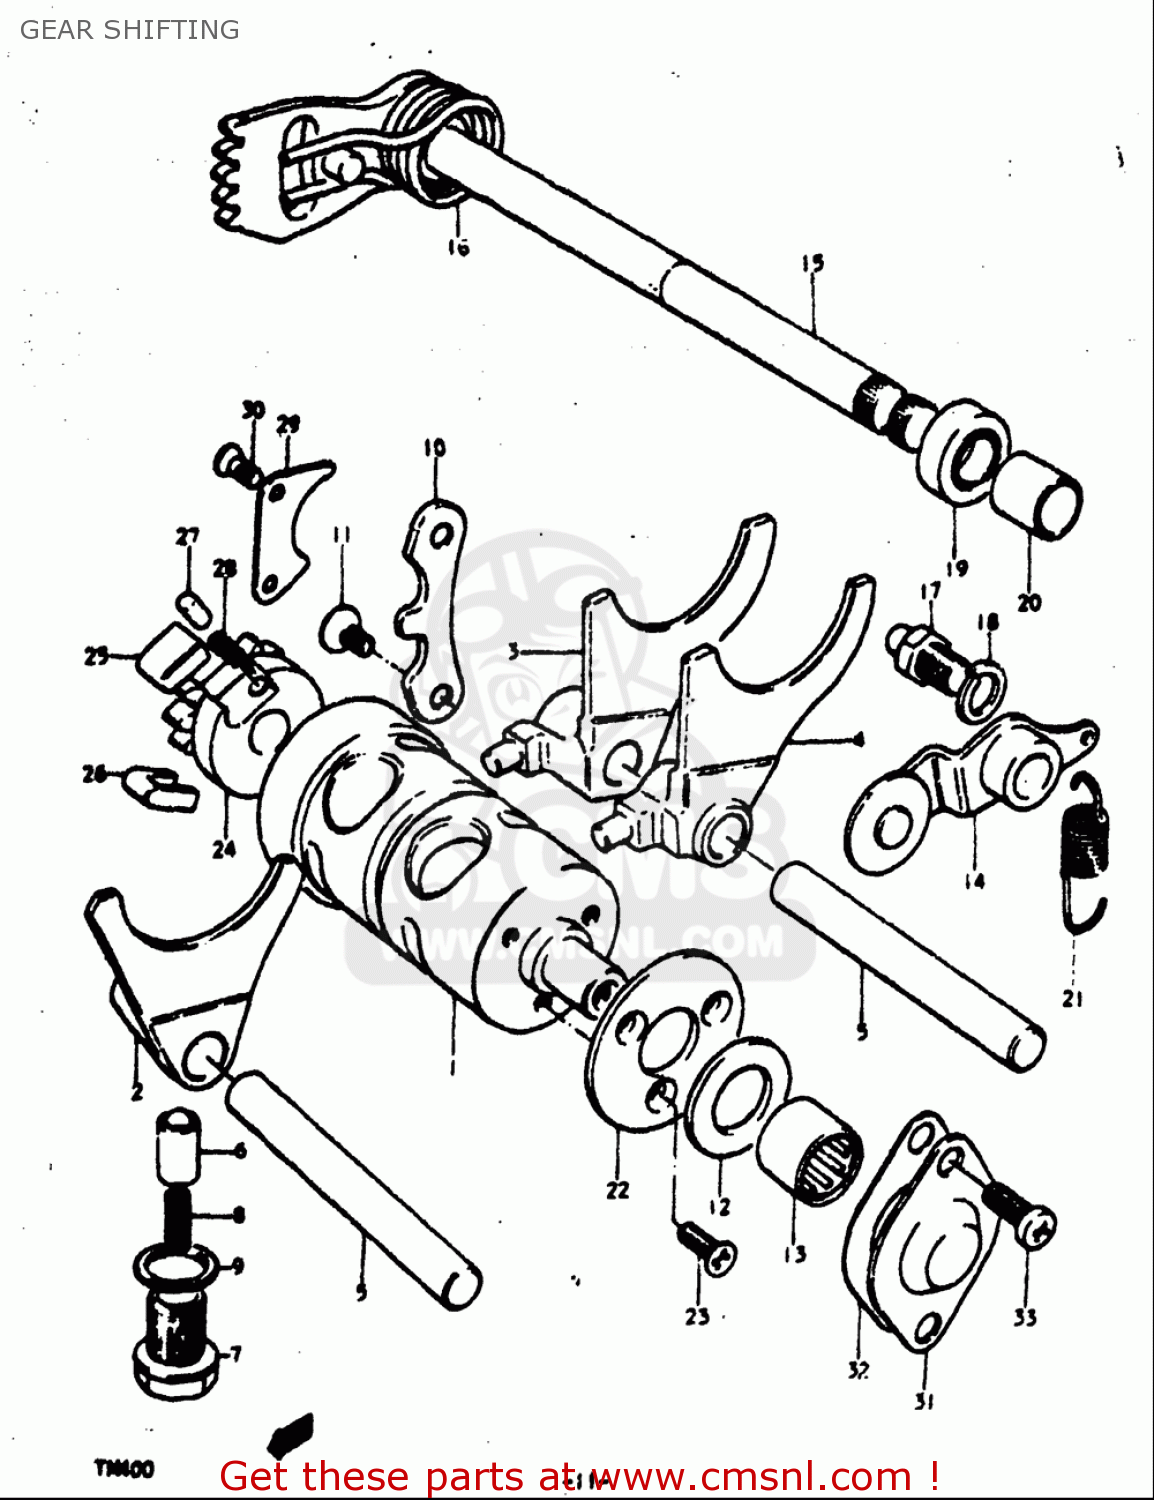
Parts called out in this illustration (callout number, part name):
5	SHAFT,GEAR SHIFT FORK
6	STOPPER,GEAR SHIFT CAM
7	HOUSING,GEAR SHIFT CAM STOPPER
8	SPRING
9	GASKET(14X19.2X2) (NAS)
11	SCREW
14	STOPPER,GEAR SHIFTING
16	SPRING
17	STOPPER,GEAR SHIFT ARM
18	WASHER,LOCK
19	SEAL,OIL (12X22X9)
20	CUSHION
21	SPRING
23	SCREW
24	GEAR,GEAR SHIFT CAM DRIVEN
25	PAWL,GEAR SHIFT NO.1
26	PAWL,GEAR SHIFT NO.2
27	PIN(5X8)
28	SPRING
30	SCREW
31	CAP,CAM PIVOT
33	SCREW
